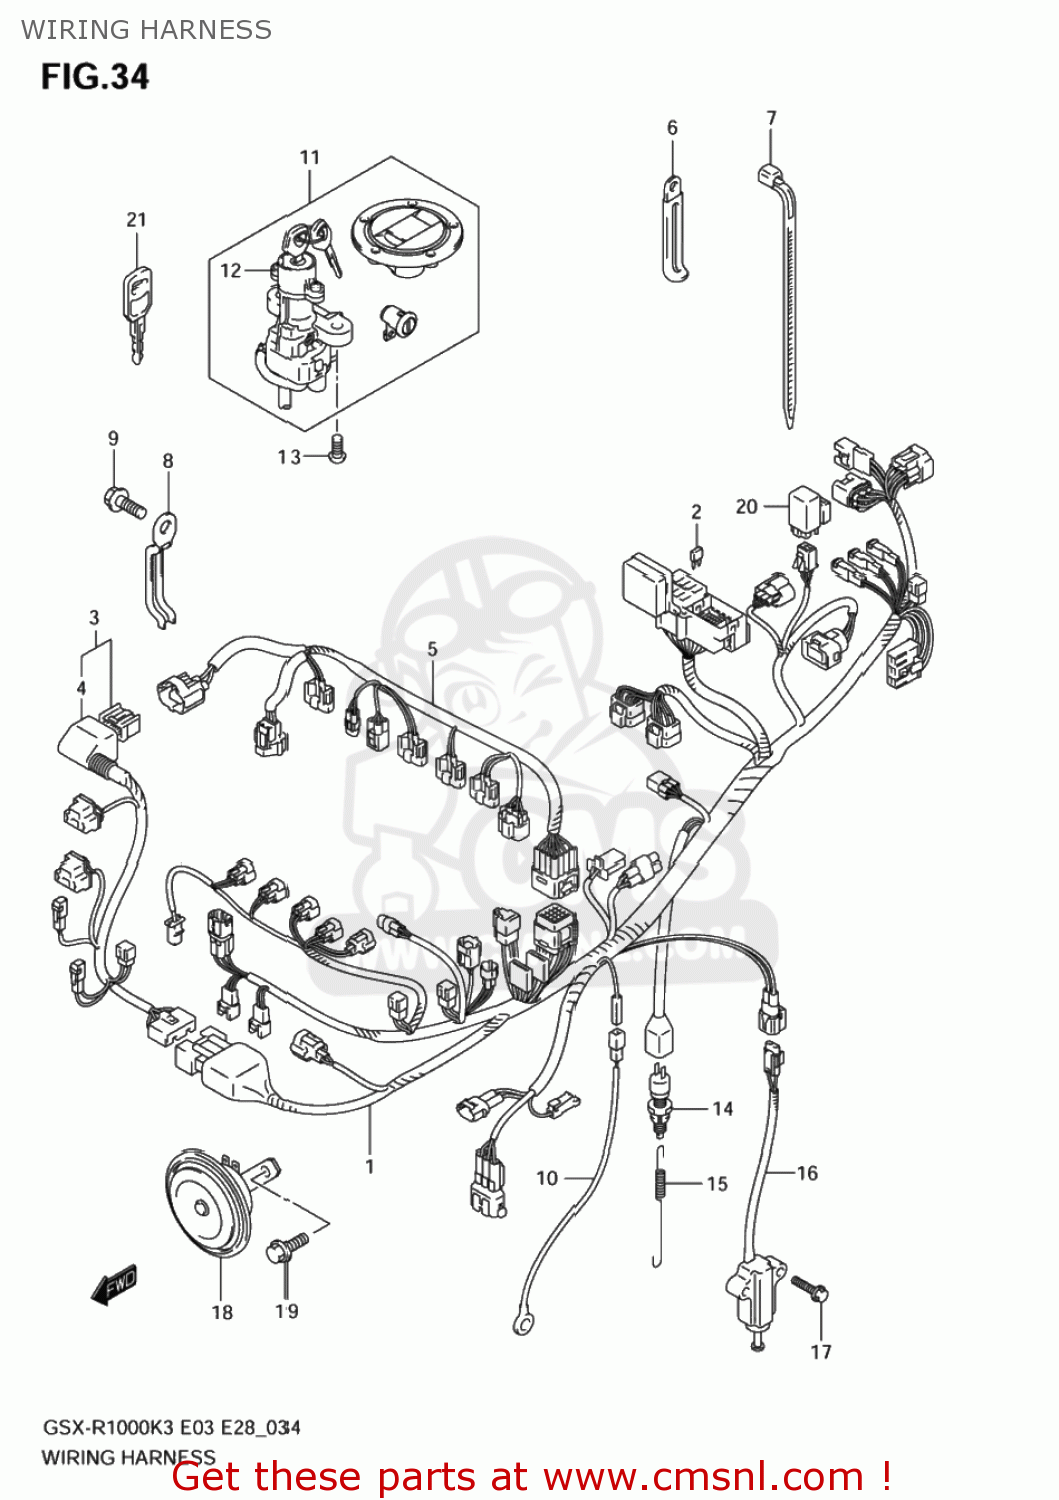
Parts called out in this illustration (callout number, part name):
1	HARNESS,WIRING NO.1
2	FUSE(10A)
3	HARNESS,WIRING NO.2
4	COVER,SPEEDOMETER COUPLER
5	WIRE,INJECTION LEAD
6	CLAMP(L:45)
7	CLAMP(L:125)
8	CLAMP
9	BOLT
10	WIRE,OIL PRESSURE SWITCH LEAD
11	LOCK SET
12	LOCK ASSY,STEERING
13	BOLT(8X20)
14	SWITCH ASSY,STOP LAMP
15	SPRING
16	SWITCH ASSY,SIDE STAND
17	BOLT
18	HORN ASSY
19	BOLT
20	RELAY ASSY
21	KEY,BLANK
